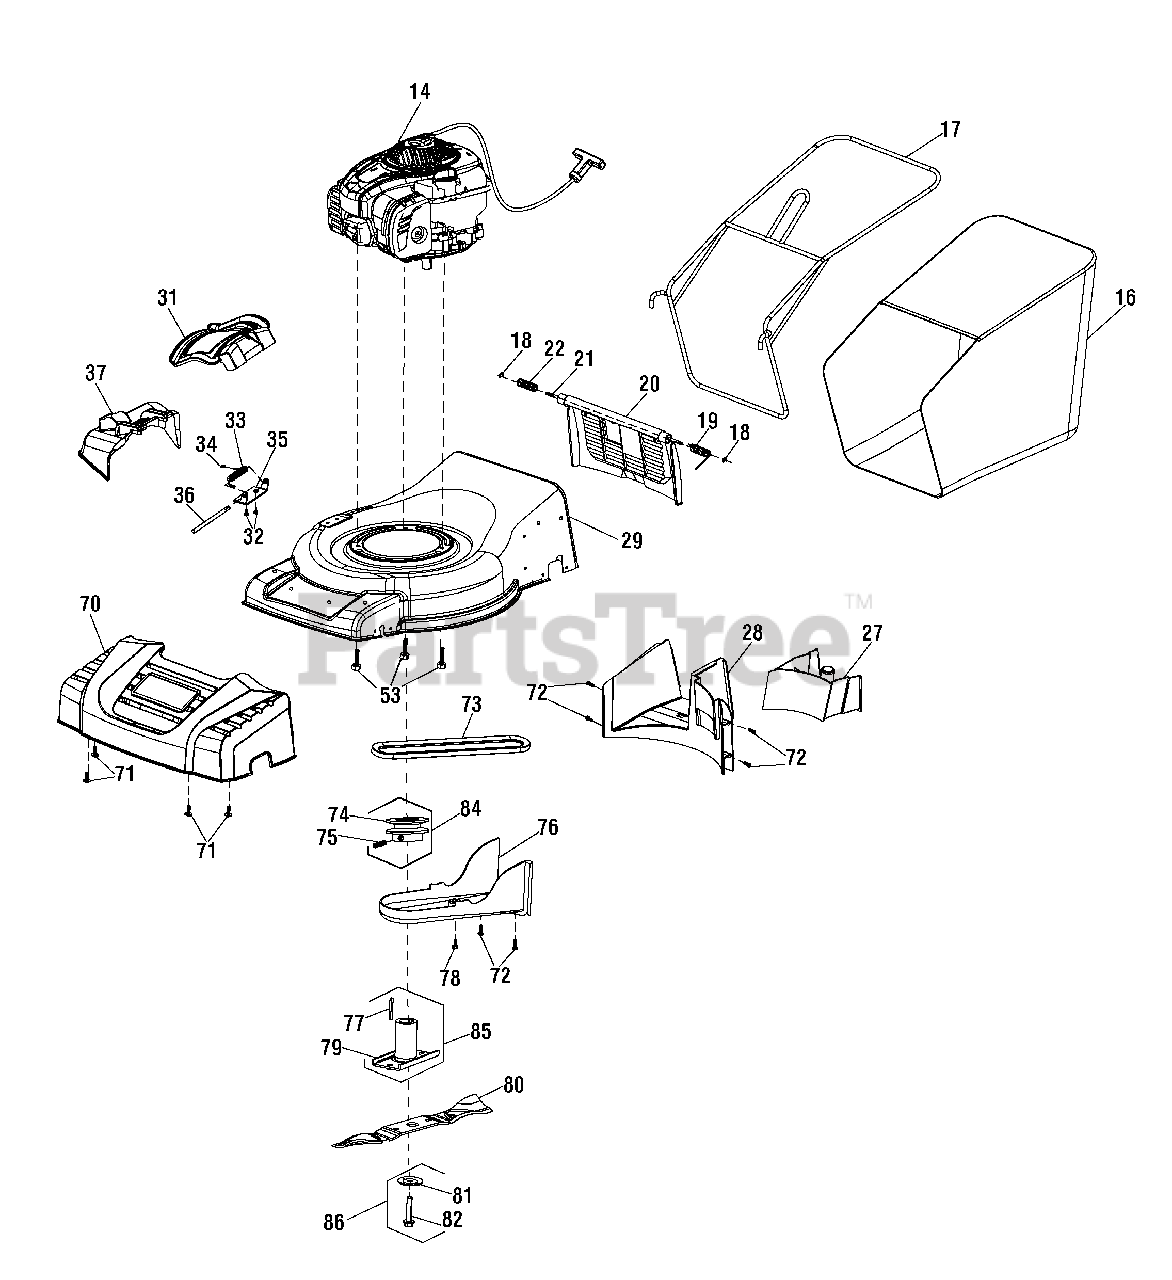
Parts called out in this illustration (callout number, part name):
14	* ENGINE, Briggs & Stratton 675EXI Series
16	BAG, Grass
17	FRAME, Grass Bag
18	CIRCLIP
19	SPRING, Left
20	REAR FLAP
22	SPRING, Right
27	MULCH PLUG
28	HOUSING, Rear
31	COVER, Side Discharge
32	BOLT, M6 x 10
33	SPRING, Torsion
34	CAP, Spring
35	BRACKET, Deflector
36	ROD, Discharge Chute
37	CHUTE, Side Discharge
53	BOLT, Self Tap
70	FRONT COVER
71	SCREW, With Washer, ST4.8 X 13
72	SCREW, With Washer, ST4.8 X 13
73	V BELT, With Teeth
74	MOUNT-VIBRATION
75	SCREW, Set, M6 x 10
76	COVER, Belt
78	BOLT, Hex Flange, Heavy Series M6 x 10
79	ADAPTER, Blade
81	WASHER, Cone
82	BOLT, Blade, 3/8-24 UNF
84	KIT, Belt Pulley
85	KIT, Blade Adapter
86	KIT, Hardware, Blade Bolt
